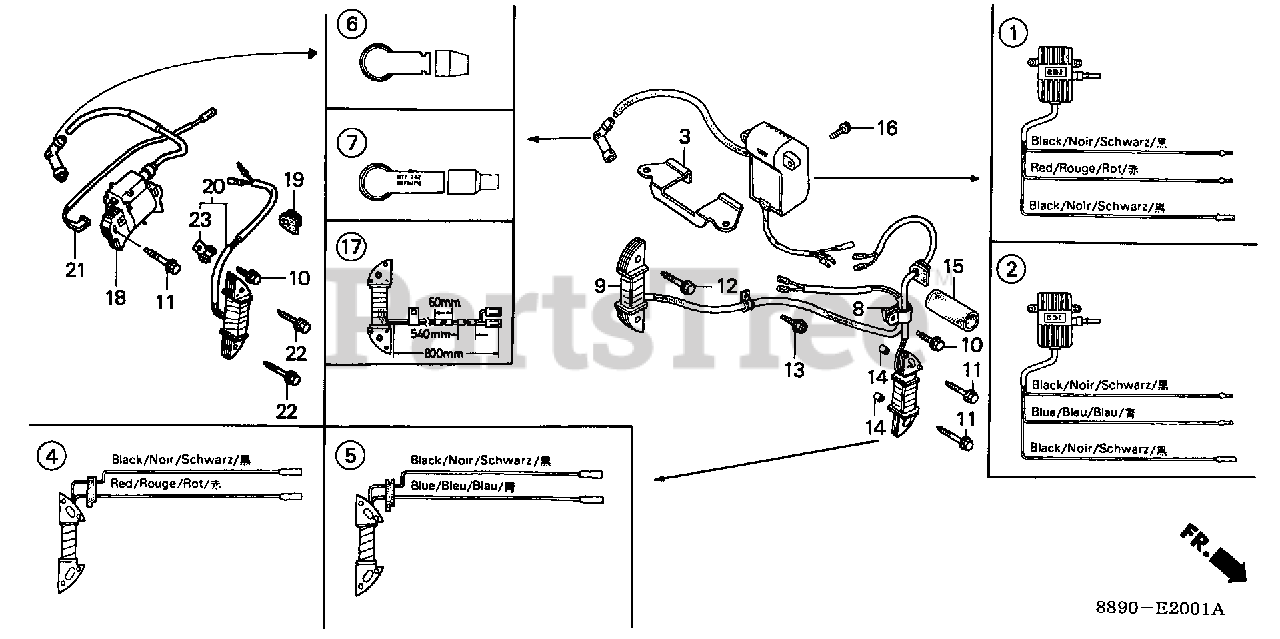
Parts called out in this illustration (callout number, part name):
1	MODULE, IGNITION CONTROL (CDI)
3	STAY, IGNITION CONTROL MODULE (CDI)
4	COIL ASSY., EXCITER
6	TERMINAL ASSY., IGNITION (NOT AVAILABLE)
6	TERMINAL ASSY., IGNITION
7	CAP ASSY., NOISE SUPPRESSOR
8	CLAMP, IGNITION WIRE
10	BOLT, FLANGE (6X12) (CT200)
11	BOLT, FLANGE (6X28) (CT200)
14	PIN, DOWEL (8X14)
15	HOSE, BULK (22X27X1000) (22X27X60)
16	BOLT, FLANGE (6X12)
